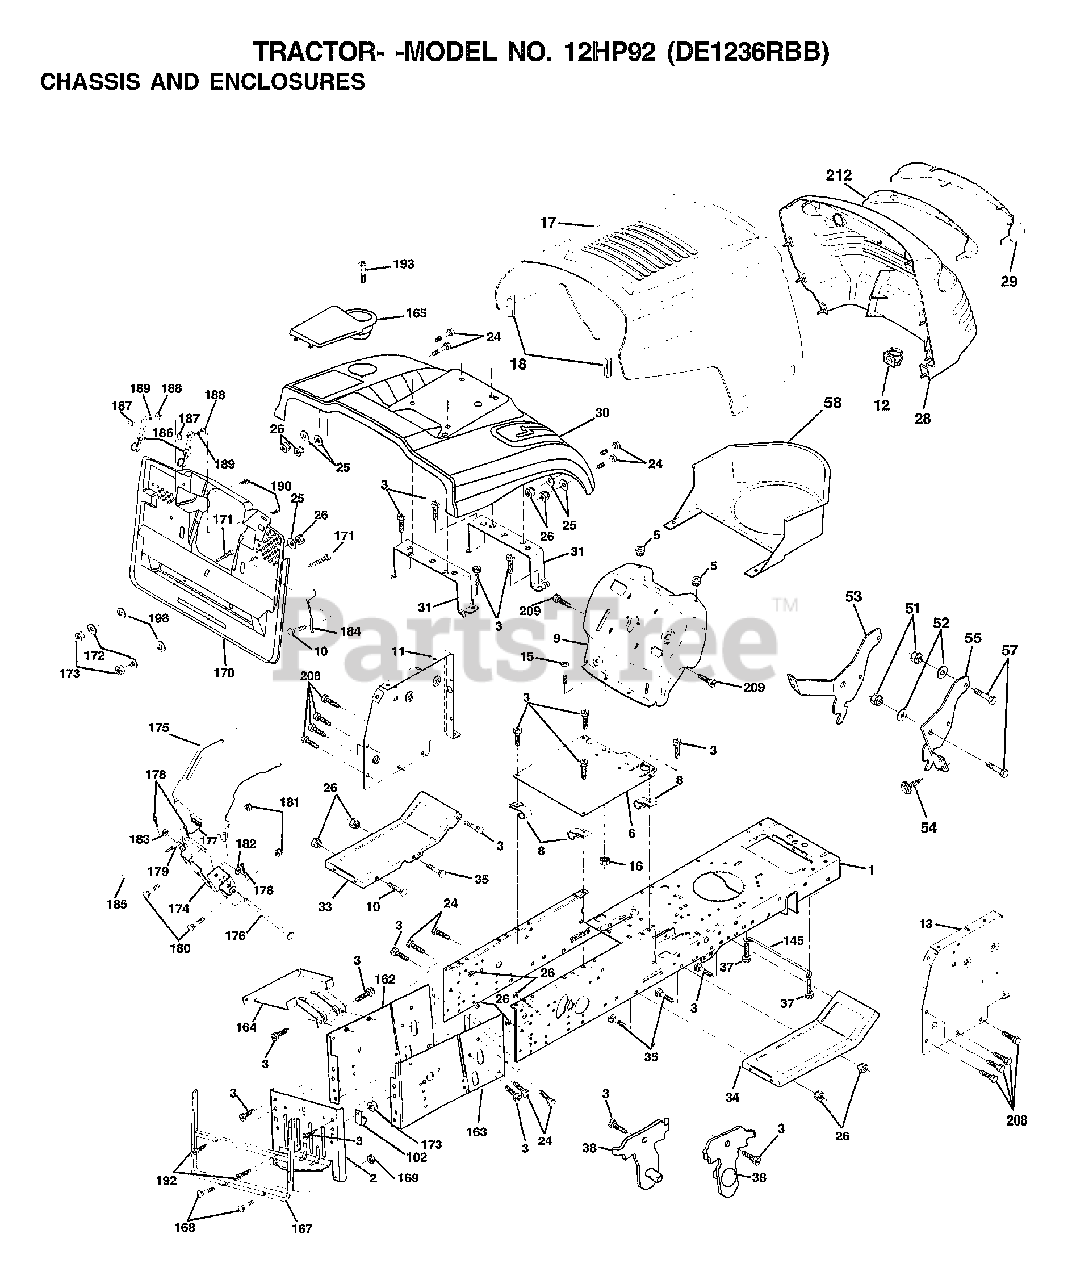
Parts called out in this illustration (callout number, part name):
2	DRAWBAR.CRD
3	SCREW
5	BUMPER-HOOD/DASH
6	SADDLE
8	"CLIP,INSULATOR"
9	DASH
11	"PANEL-DASH,LH"
12	CLIP.TINNERMAN
15	SCREW
24	BOLT
25	WASHER
26	NUT
30	FENDER.CRD.SAGE
31	BRKT.SUPT.FENDER.CRD
33	FOOTREST
34	FOOTREST.PNT.RH
35	BOLT
37	SCREW LT
38	BRKT ASM PIVOT MOWER REAR
51	NUT
52	WASHER
53	BRACKET.GRILLE.LH
54	SCREW.HEX.WS.HD
55	BRACKET.GRILLE.RH
58	AIR DUCT
102	CLIP T
145	"ROD POVOT,CHASSIS"
162	BRKT.EXT.CHASSIS.LH.CRD
163	BRKT.EXT.CHASSIS.RH.CRD
164	SUPPORT.BATTERY.CRD
165	COVER.BATTERY.CRD.BLACK.LT
167	SUPT.ASM.BACKPLATE
168	BOLT-RD HD SQ NK
170	COVER.BACKPLATE.BLACK
171	BOLT.HEX.3/8-16X2-1/2
173	NUT
174	BRKT.SWITCH.FBI.CRD
175	GRUARD.DOOR.REAR.CRD
176	HINGE PIN
177	SPRING.COVER.LH
179	ROD.PIVOT.FBI.CRD
182	WASHER.385X.625
183	WASHER
184	BRKT.ACTUATOR.BAG.CRD
185	TUBE.LEVER.SWCH.FBI.CRD
186	LATCH ASSY.BAGGER
187	WELDNUT
188	WASHER #10
189	LOCKWASHER
190	SCREW
192	SCREW LT
193	SCREW
198	NUT PUSH
208	SCREW
209	SCREW
212	INSERT LENS REFLECT
